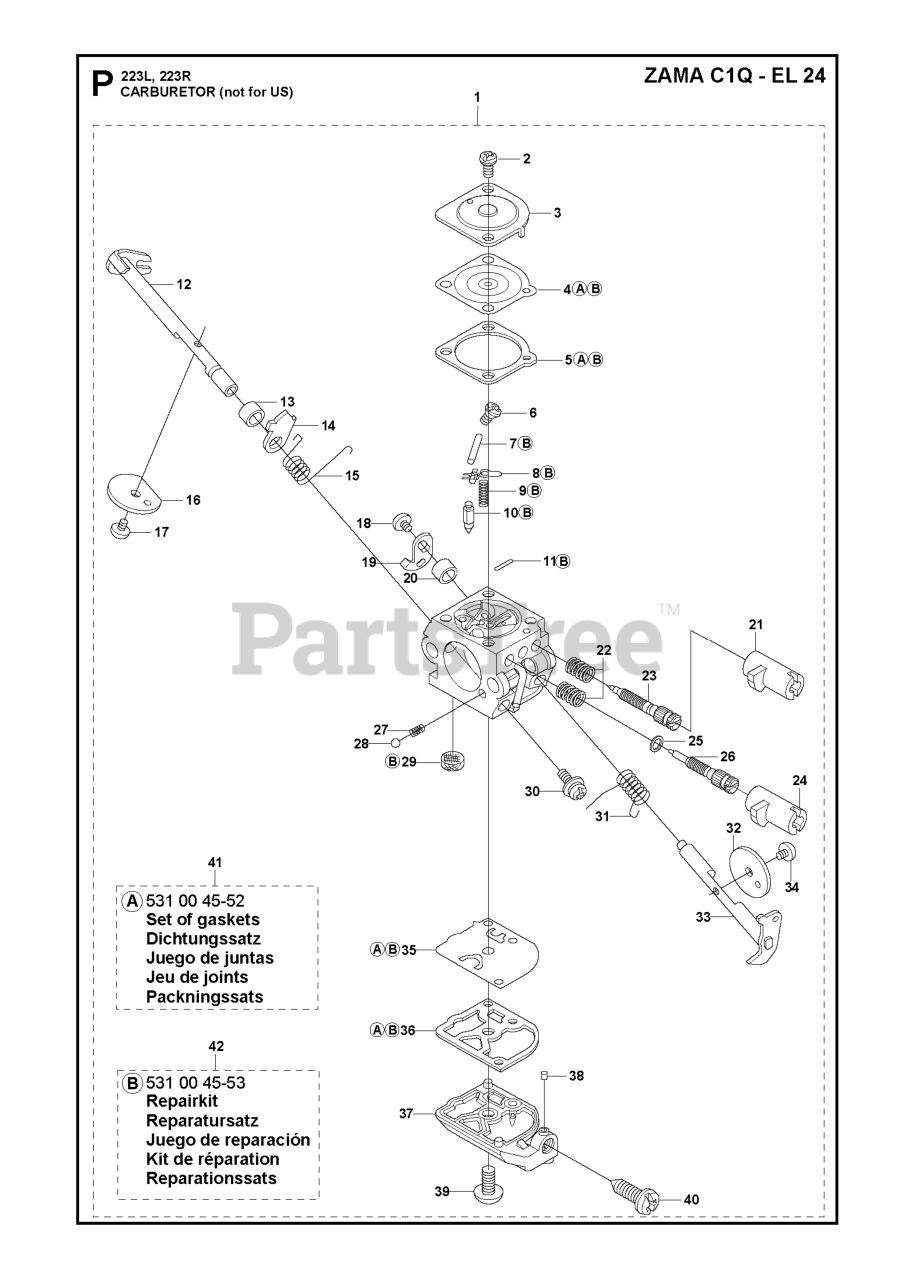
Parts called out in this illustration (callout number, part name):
1	CARBURETOR
7	PIN RETAINING SCREW
9	SPRING
10	INLET NEEDLE
12	CHOKE SHAFT
22	SPRING
23	LOW SPEED NEEDLE
26	NEEDLE HIGH SPEED
31	SPRING THROTTLE
32	THROTTLE FLAP
35	PUMP DIAPHRAGM
